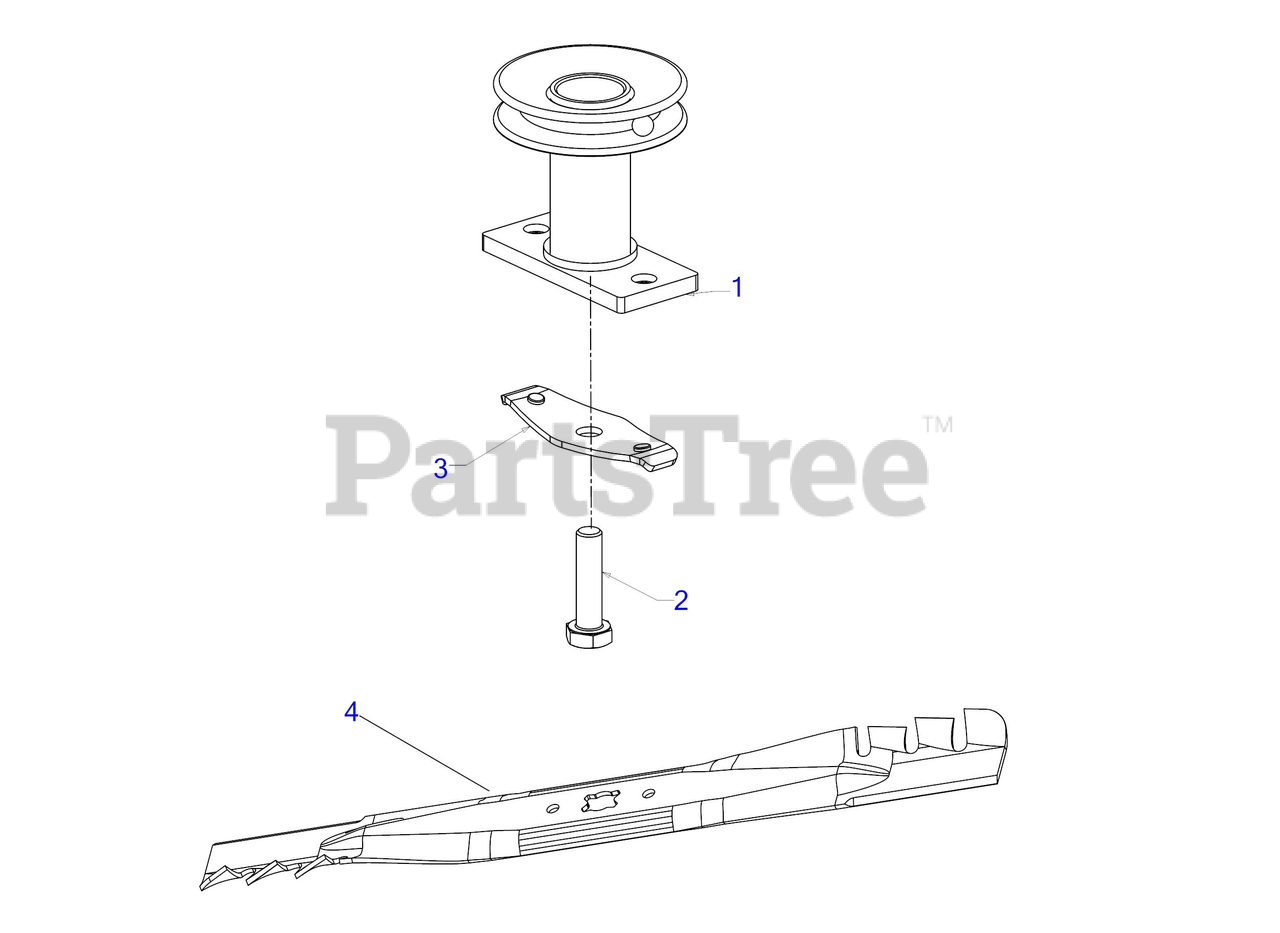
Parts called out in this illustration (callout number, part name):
1	DRIVE PULLEY
2	SCREW 3/8-24 x 1.50 GR8
3	BLADE BELL SUPPORT
4	21" BLADE (XTREME)
